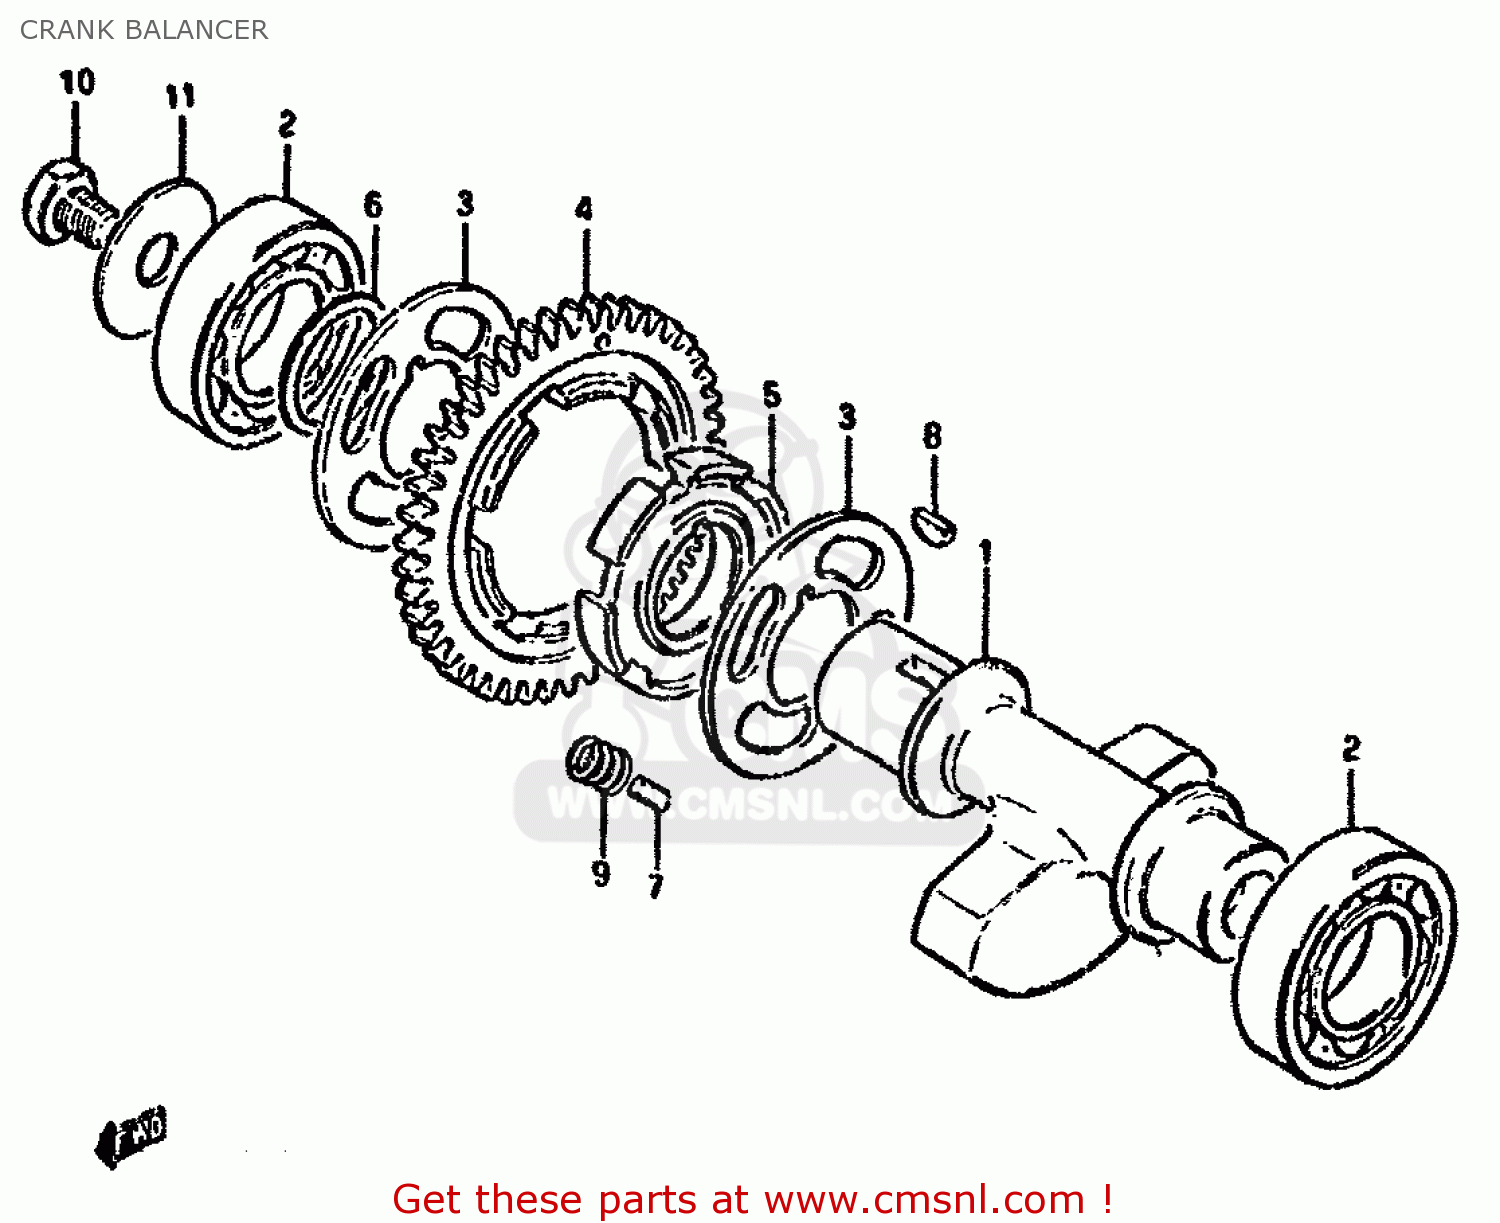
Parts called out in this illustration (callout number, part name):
1	SHAFT,CRANK BALANCER
2	BEARING(25X62X17)
3	WASHER
4	GEAR,CRANK BAL DRIVEN(NT:46)
5	RACE,CRK BAL DRIVEN GR INNER
6	SHIM
7	PIN
8	KEY 4MM
9	SPRING
10	Bolt
11	WASHER(12X40X2.5)
